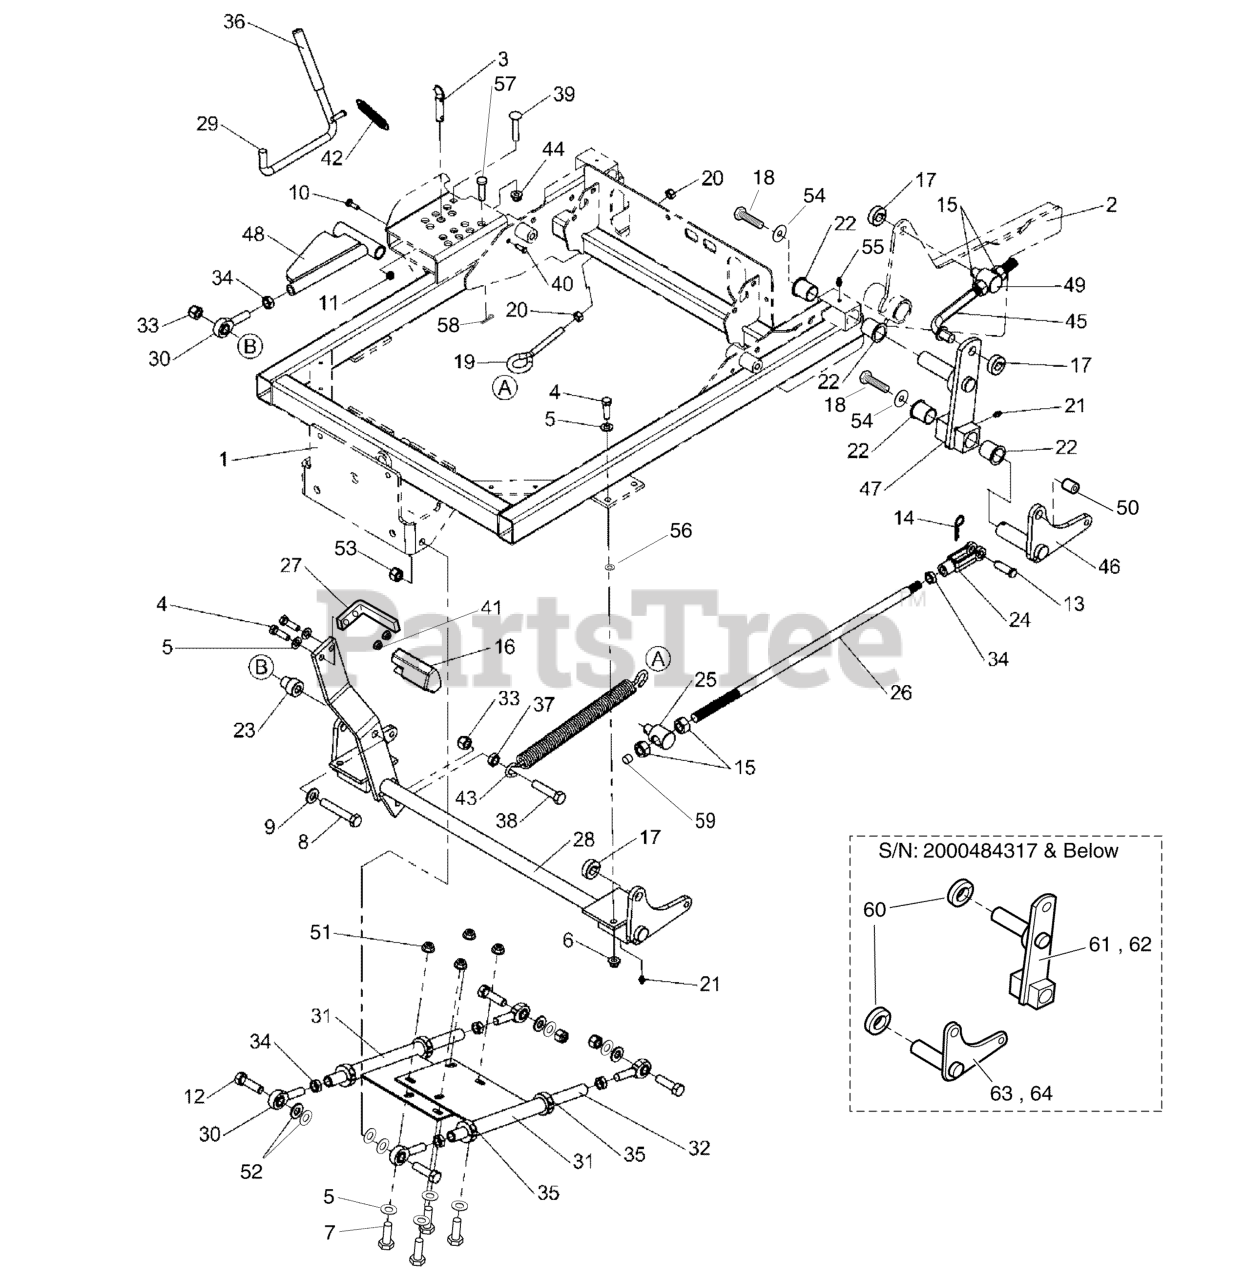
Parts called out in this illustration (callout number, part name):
1	MAIN FRAME
2	MOTOR MOUNT
3	HITCH PIN, 1/2 X 2"
4	BOLT, 3/8-16 X 1-1/4" GD5 CZ
5	WASHER, 3/8 GR. 9 FLAT
6	NUT, 3/8-16 Hex Nylock Flange
7	BOLT, 3/8-16 X 1" GD5 CZ
8	BOLT, 1/2-13 X 3" GD5 CZ
9	WASHER, 1/2 SAE
10	HHCS, 1/4-20 X 0.625, GR5, ZINC/CLEAR
11	NUT, 1/4-20 HEX SERR. FLANGE
12	BOLT, 1/2-20 X 1-3/4" GD8 CZ
13	CLEVIS PIN, 1/2" X 1-1/2"
14	HAIR PIN CLIP
15	NUT, 5/8-11 HEX
16	PEDAL, Rubber
17	COLLAR, 5/8" Split
18	BOLT, 3/8-16 X 3/4, PLT W/PATCH
19	EYE BOLT, 3/8-16 X 5, 2.88THRD, 1EYE, CZ
20	NUT, 3/8-16 Hex
21	GREASE FITTING
22	BUSHING, Flange
23	ADAPTER, CASTER AXLE, CZ
24	CLEVIS , 1/2-20, STEEL
25	SPRING ROD PIVOT
26	DECK ADJUSTMENT ROD
27	PEDAL, FOOT - BLK
28	DECK LIFT SHAFT
29	WELD, ROD DECK LIFT - BLK
30	BALL JOINT, 1/2-20 Male
31	DECK STABILIZER
32	DECK STABILIZER SHAFT
33	NUT, 1/2-13 HEX NYLON LOCK
34	NUT, 1/2-20 Hex Jam
35	COLLAR, 3/4" Split
36	GRIP
37	NUT, 1/2-13 Hex Jam
38	BOLT, 1/2-13 X 2-1/4" GD5 CZ
39	CARRIAGE BOLT, 3/8-16 X 2"
40	PIN, CLEVIS, 1/4 X 7/8, PLATED
41	NUT, 3/8-16 HEX NYLON LOCK
42	SPRING, Extension
43	DECK LIFT SPRING
44	NUT, 3/8"-16 SIDE LOCK
45	DECK LIFT ROD
48	DECK ADJUST LINK
50	BUSHING, .510 X .625 X .500
51	NUT, 3/8"-16 SERRATED FLANGE
52	WASHER, 1/2 SAE
53	NUT, Hex, Nylon Lock, 1/2-20
54	FLAT WASHER, THICK
55	GREASE FITTING 45
56	WASHER, 3/8 SAE
57	PIN, CLEVIS, 1/2 X 2 YZP
58	PIN, COTTER, 1/8 X 1-1/4
59	CAP, VINYL - .562 X .750 - BLK
60	COLLAR, 1" SPLIT
61	ASSM, REAR LIFT, L
62	ASSM, REAR LIFT, R
63	WELD, PIVOT, DECK LIFT - L
64	WELD, PIVOT, DECK LIFT - R
